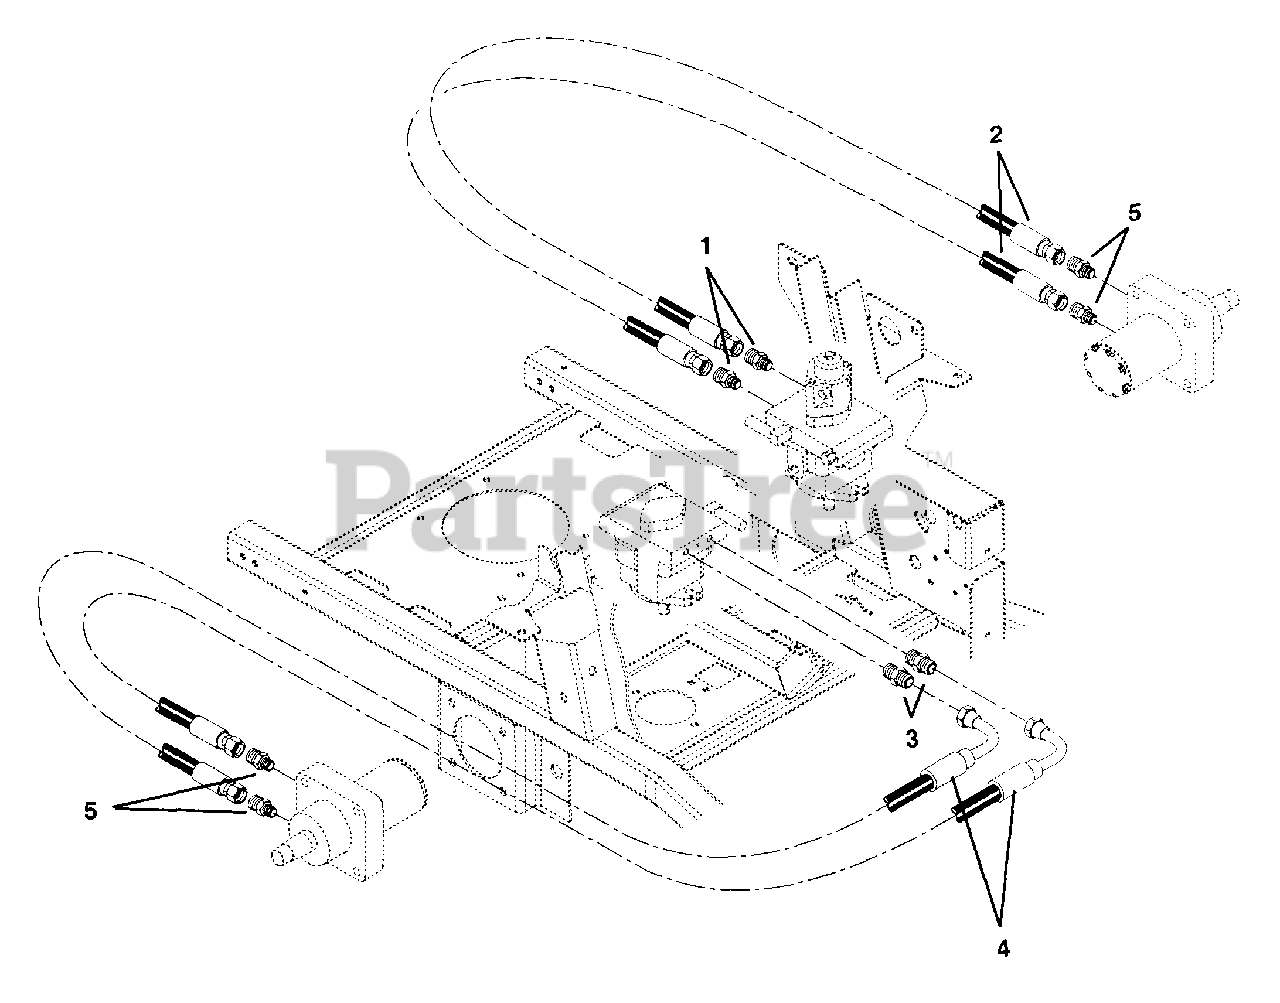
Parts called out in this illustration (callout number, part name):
1	Adapter-Hydraulic Steel .75 to .75
2	Hose-Hydraulic .50 18.75 Long
3	Adapter-Hydraulic Steel .75 to .75
4	Hose-Hydraulic .50 32 Long
5	Adapter-Hydraulic Steel 7/8 to 3/4
